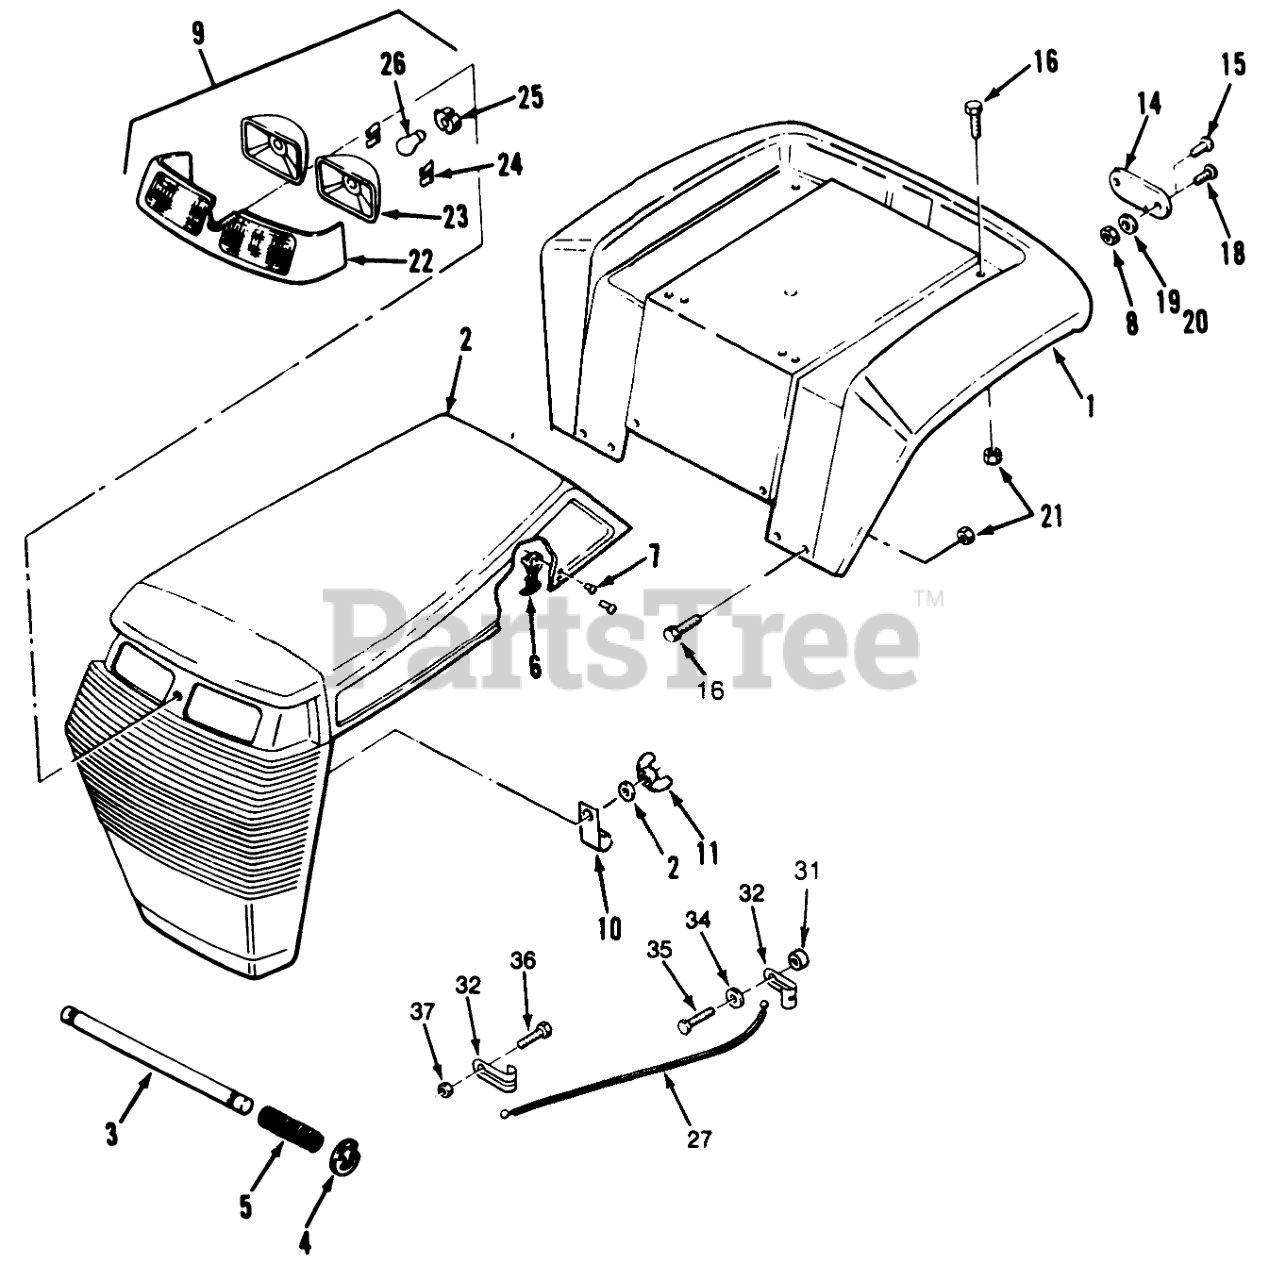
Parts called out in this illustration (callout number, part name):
1	FENDER R
2	Hood & Grill
4	E-Ring
5	SPRING
6	HANDLE ASM
7	RIVET-POP
8	Nut
9	Head Light Bar (Includes Ref. #22, 23, 24, 25, & 26)
10	J-CLIP
11	Nut-Wing
12	WASHER
14	Reflector
15	Poprivet
16	BOLT-CARR
18	Screw
19	WASHER
20	Lockwasher
21	NUT-LOCK, NI
22	LIGHT-BAR BLACK
23	LIGHT POD
24	RETAINER
25	SOCKET-HEADLIGHT
26	BULB
27	CABLE-ASS'Y
31	Spacer
32	CLEVIS
34	Washer
35	Bolt
36	Screw-Machine
37	Nut
